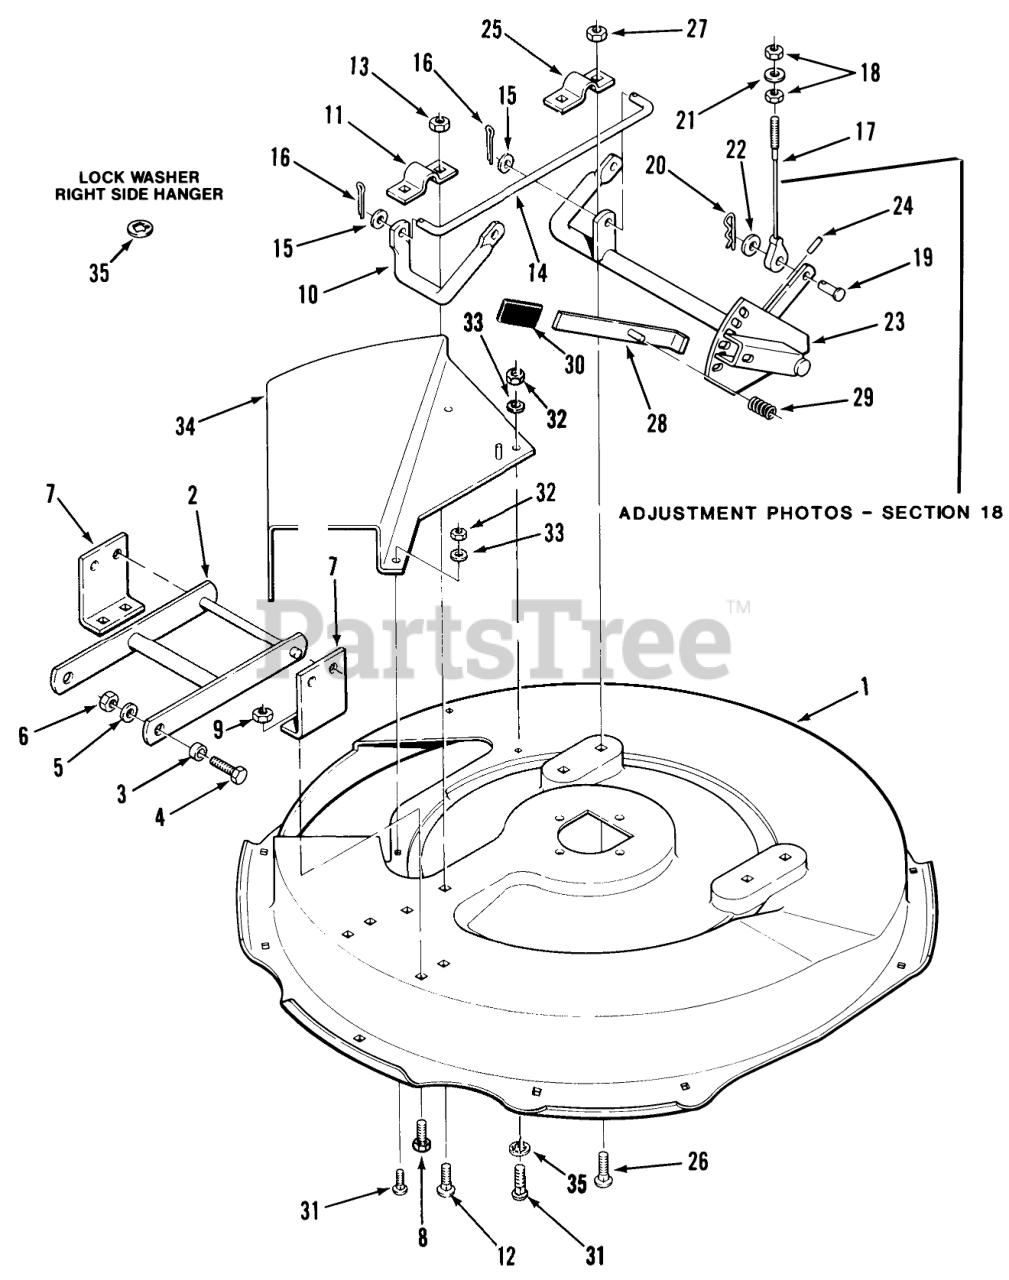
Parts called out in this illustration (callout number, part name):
1	DECK 30" MOWER R
2	ASSY MWR FRONT MO R
3	SPACER
4	BOLT
5	Washer
6	NUT
7	BRKT FRONT MOWER R
8	BOLT
9	NUT
10	ROD HEIGHT ADJ R
12	Bolt
13	NUT
14	ROD HEIGHT ADJUST
15	Washer
16	Cotter Pin
17	CABLE MOWER SUPPORT
18	Nut
19	CLEVIS PIN
20	Hairpin
21	WASHER 5/16 SAE
22	Washer
23	HEIGHT ADJ ASSY R
24	SPIROL PIN
26	Bolt
27	NUT
28	LEVER ASSY
29	SPRING-COMPRESSION
31	Bolt 1/4-20 X 5/8
32	Nut
34	Mower Deflector
35	Washer-Lock
